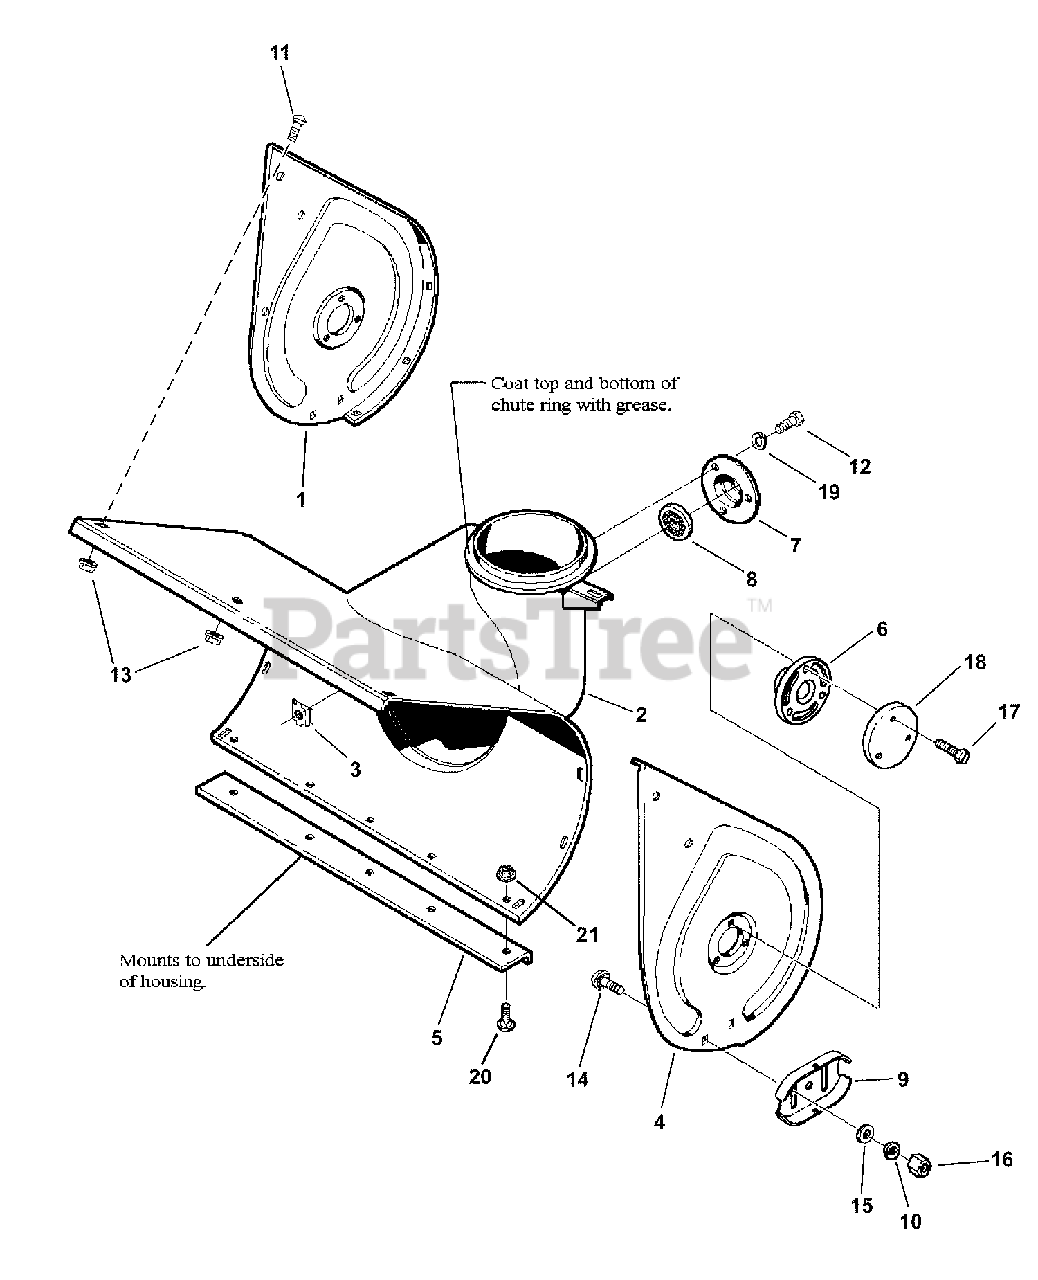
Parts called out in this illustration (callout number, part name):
1	END PLATE, RH- Auger Housing- Red
2	WELDMENT, Auger Housing - 22" - Red
2	WELDMENT, Auger Housing - 24" - Red
3	RETAINER NUT, 5/16-18
4	END PLATE, LH- Auger Housing- Red
5	BLADE, Scraper- 22"
5	BLADE, Scraper- 24"
6	BEARING, Auger
7	RETAINER, Bearing
8	BALL BEARING
9	SKID SHOE, Reversible- Red
10	WASHER, 3/8" Split Lock
11	BOLT, 1/4-20 x 1/2" Short Square Neck Carriage, GR 5
12	SCREW, 5/16-18 x 5/8 Hex Head Cap, GR 5
13	NUT, 1/4-20 Hex Flange Lock Large
14	BOLT, 3/8-16 x 3/4" Square Neck Carriage
15	WASHER, 3/8" Flat
16	NUT, 3/8-16 Hex Nyloc
17	SCREW, 5/16-18 x 1" Hex Washer Self-Tap
18	CAP, Bearing, Red
19	WASHER, 5/16" Split Lock
20	BOLT, 1/4-20 x 7/16" Short Square Neck Carriage, GR 5
21	NUT, 1/4-20 Hex Flange Lock
